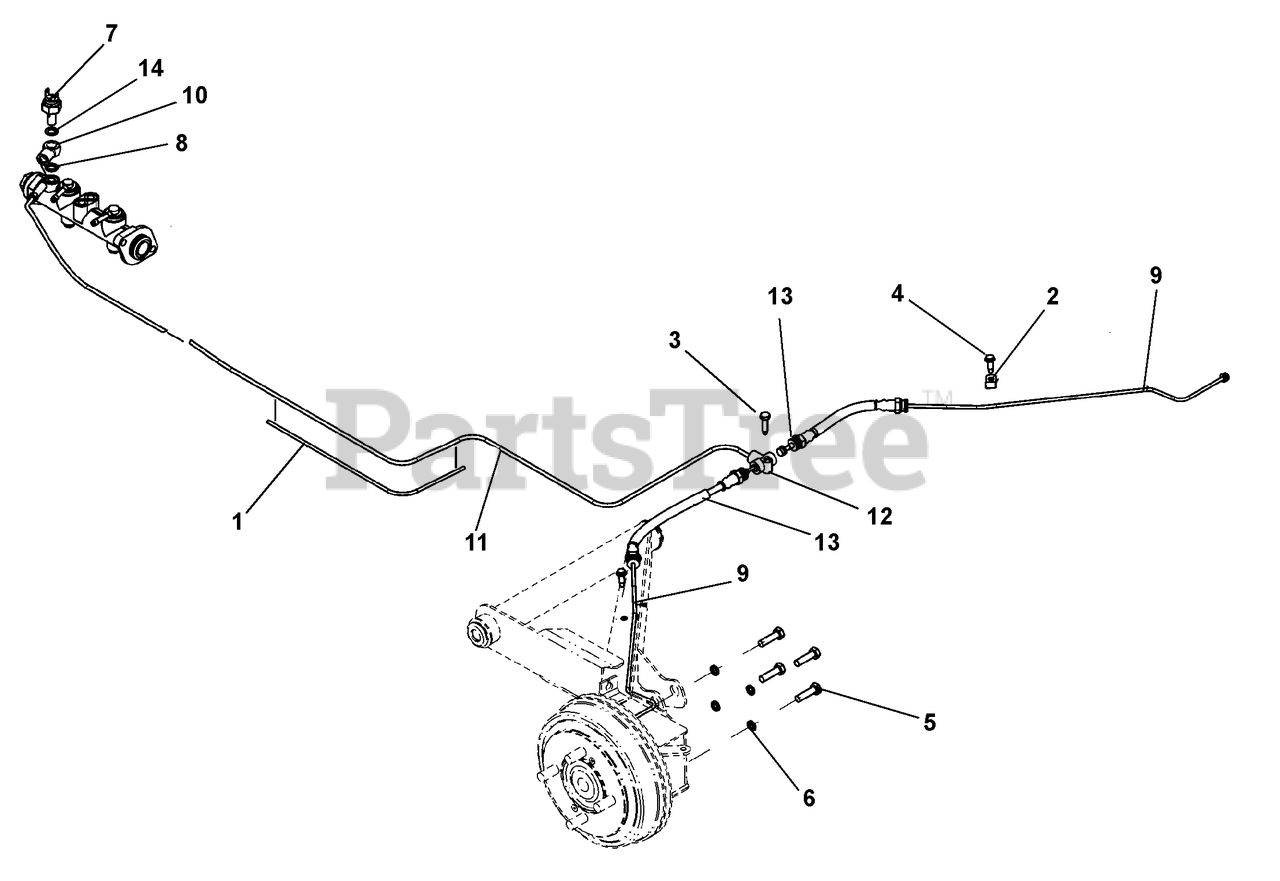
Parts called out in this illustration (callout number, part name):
1	CORRUGATED LOOM, .125 ID
2	WIRING/TUBE CLIP FOR 1/4 OD
3	SCREW HHC SELF-TAP 1/4-20X 1
4	HH DRILL SCREW 1/4 X 3/4LG
5	HHCS M8X1.25X30 GR10.9 YLW PLT
6	WSHR-LK M8 YWZC
7	BRAKE SWITCH, HIGH PRESSURE
8	WASHER, COPPER, 3.5 MM
9	REAR, BRAKE HARD LINE
10	BULK HEAD FLOW THROUGH
11	BRAKE, LINE MAIN
12	FITTING 3 WAY HYD.
13	REAR RUBBER BRAKE LINE
14	MSTR CYL CPPR WSHR 16X10X1.5MM
